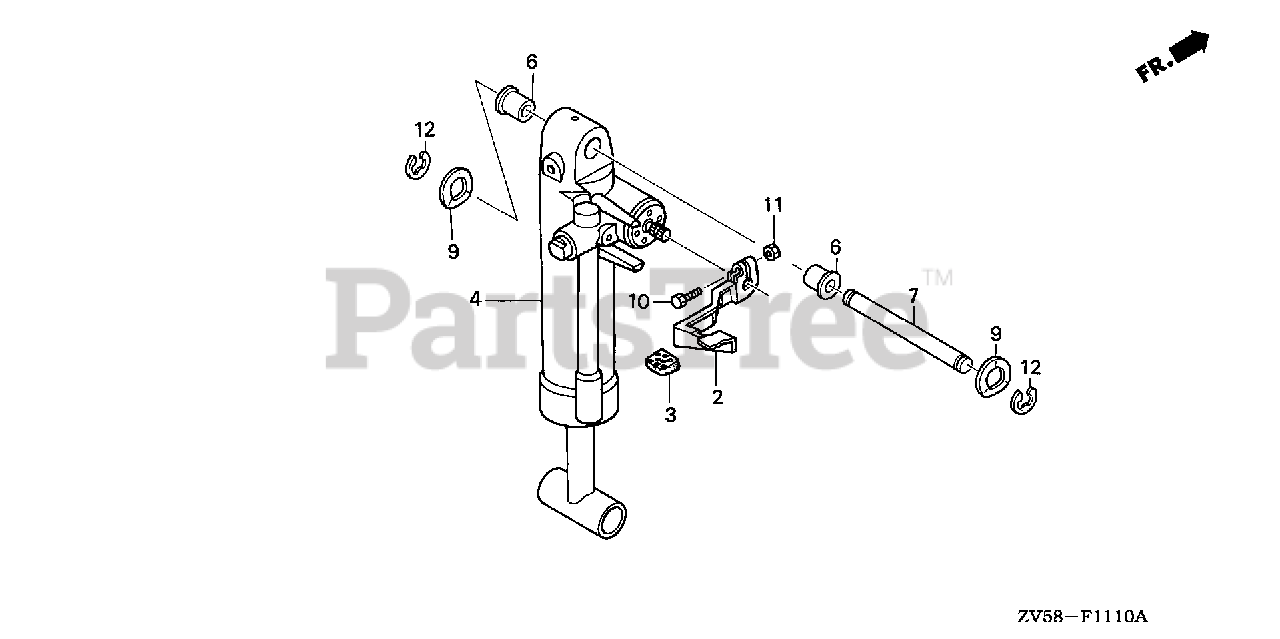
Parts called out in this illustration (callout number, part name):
2	LEVER, TILT
3	GRIP, LEVER
4	SHOCK ABSORBER ASSY. *NH283* (STIN GRAY)
6	BUSH, CYLINDER (UPPER)
7	PIN, CYLINDER (UPPER)
9	WASHER, WAVE (24MM)
10	BOLT, HEX. (6X25)
11	NUT, HEX. (6MM)
12	E-RING (10MM)
